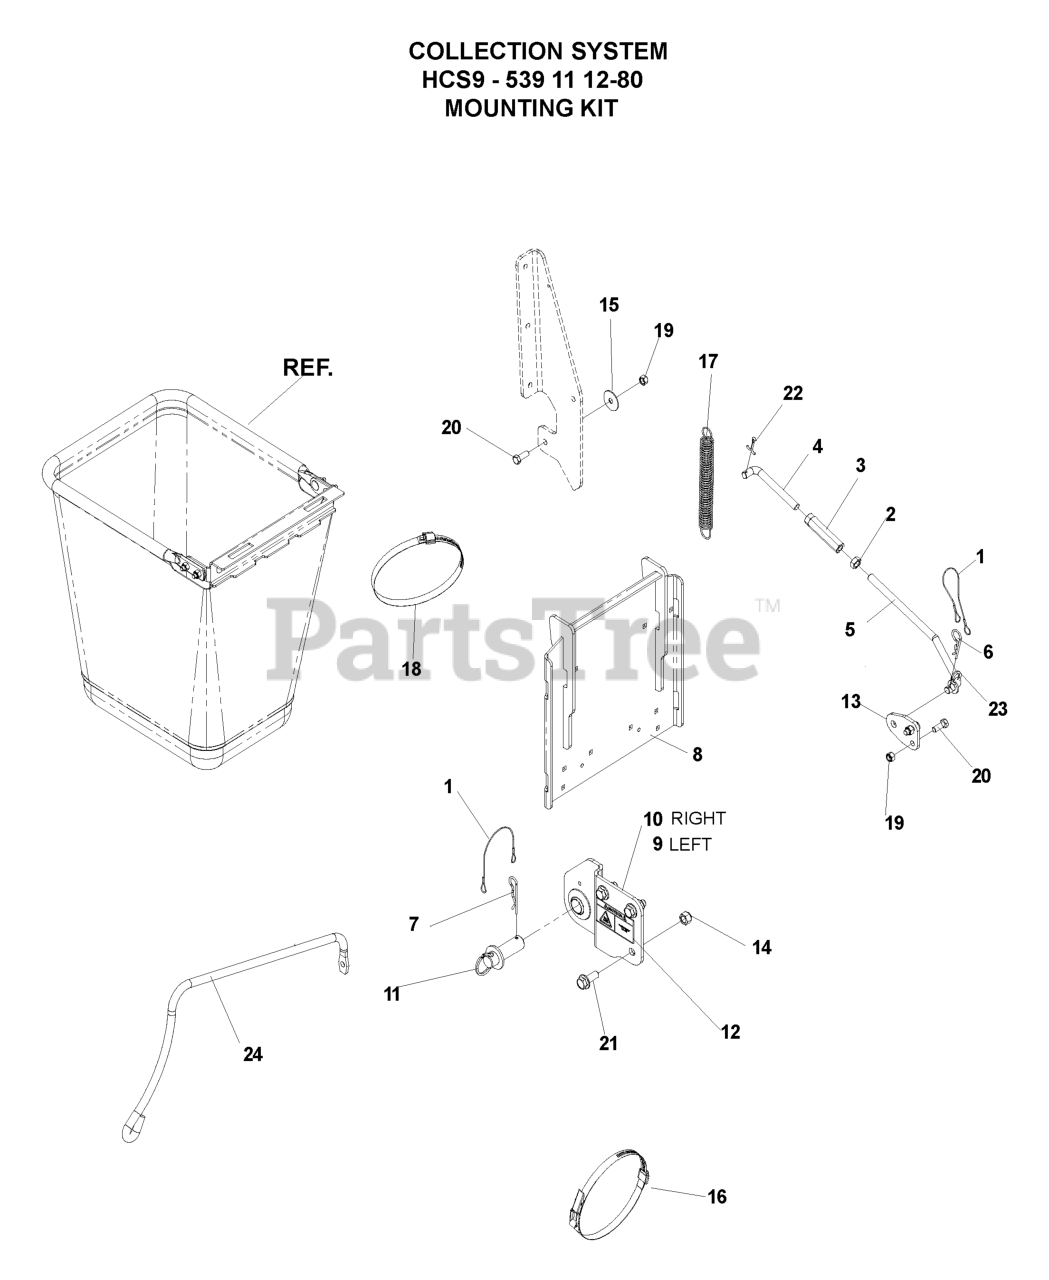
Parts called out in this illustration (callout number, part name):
2	NUT, 1/2-20, JAM
3	TURNBUCKLE, 1/2
4	SUPPORT LINKAGE, LH
5	SUPPORT LINKAGE, MID
6	PIN HAIR, 1/8 X 2 1/2
8	REAR GUARD, MID
9	HITCH BRACKET, LEFT
10	HITCH BRACKET, RIGHT
12	DECAL, HOT SURFACE
13	SUPPORT BRACKET
14	NUT, 1/2-13, NYLOC
15	WASHER, .39
16	OVERCENTER BAND
18	HOSE CLAMP
19	NUT, 3/8-16, NYLOC
20	HCS, 3/8-16 X 1 1/2, GR5
21	BOLT, 1/2-13 X 1 1/4, WHIZLK
22	PIN COTTER, 5/32 X 1 1/4
23	RING, RETAINING, SPEC
24	HOSE SUPPORT
539111280	Mounting Kit Collection System
